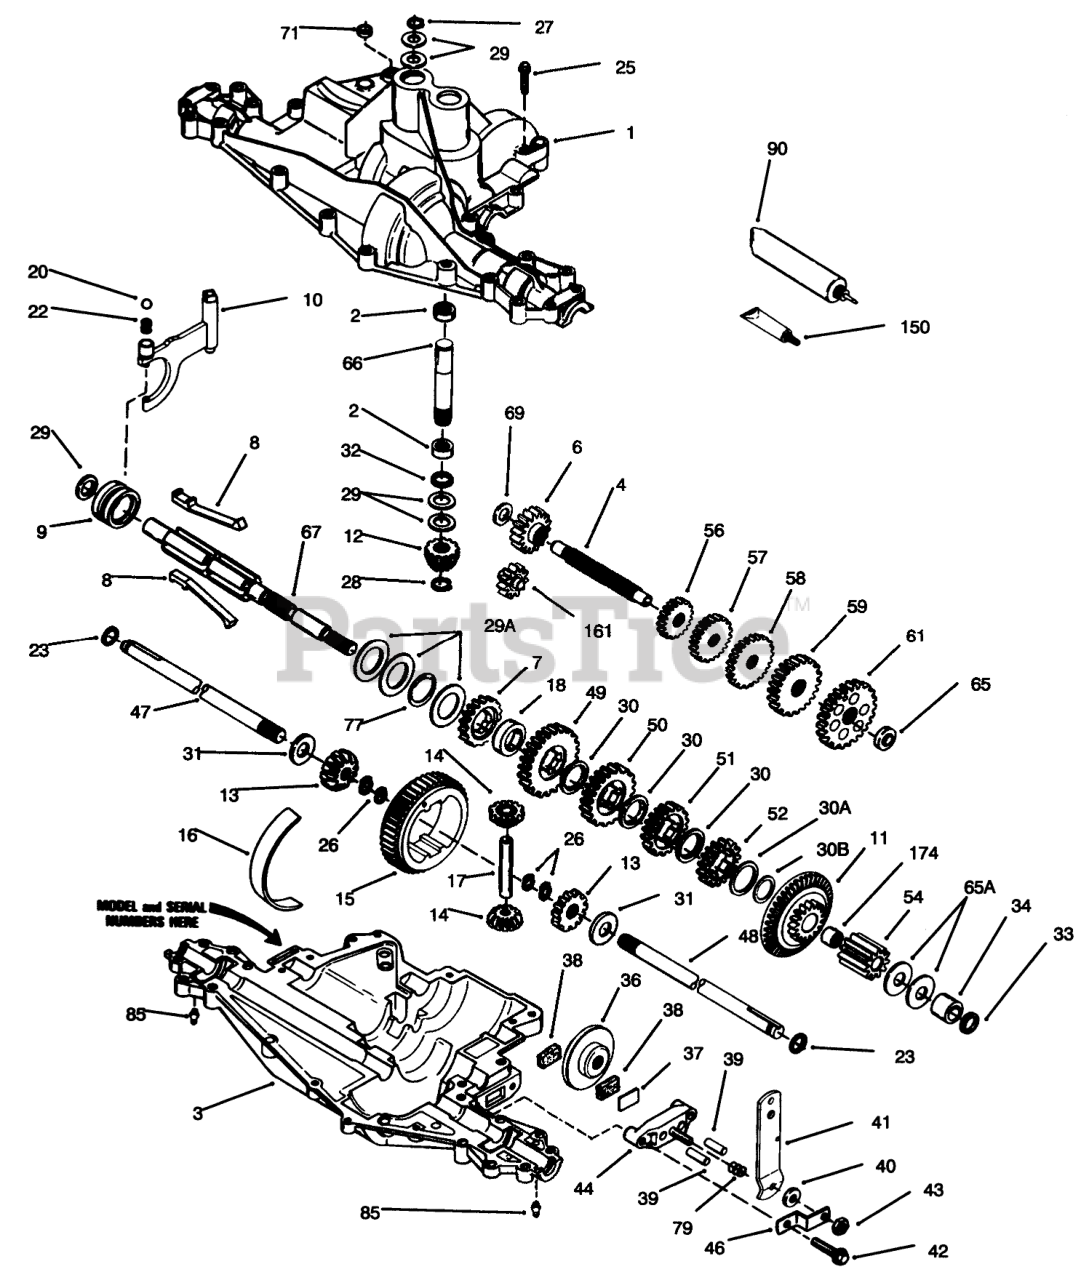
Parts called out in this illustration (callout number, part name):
1	Transaxle Cover
2	Bearing-Needle
3	Transaxle Case
4	Countershaft
6	Spur Gear (16 Teeth)
7	Gear-Spur (22 teeth)
8	Shift Key
9	Shift Collar
10	Shift Rod & Fork
11	Bevel Gear & Bearing (44/16 Teeth) (Incl. Ref. #174)
12	Bevel Pinion (14 Teeth)
13	Gear Bevel
14	Gear Pinion
15	Gear-Ring
16	Bearing Strip
17	Drive Pin
18	Neutral Spacer
20	Ball (3/8" dia.)
22	Spring
23	Ring-Seal
25	Ring Set (.020 O S)
26	Retaining Ring (pkg of 2)
27	Ring-Snap
28	Ring-Retainer
29	Washer
29A	Washer
30	Washer
30A	Washer
30B	Washer
31	Washer
32	O Ring
33	O-Ring
34	Bushing
36	Brake Disk
37	Brake Pad Plate
38	Brake Pad
39	Dowel Pin
40	Washer
41	Brake Lever
42	Ring Set (.020 O S)
43	Locknut
44	Nozzle-Carburetor
46	Bracket
47	Axle (16-3/4" Ig.)
48	Axle (11-9/16" lg.) (Incl. Ref. #26)
49	Gear-Spur, 30 Teeth
50	Gear-Spur, 25 Teeth
51	Gear-Spur (22 teeth)
52	Gear Spur 19t
54	Spur Gear (11 Teeth)
56	Gear-Spur, 20 Teeth
57	Gear-Spur, 25 Teeth
58	Gear-Spur (28 teeth)
59	Gear-Spur (30 teeth)
61	Spur Gear (34Teeth)
65	Washer
65A	Washer
66	Input Shaft (3.522" Ig.)
67	Shifter & Brake Shaft
69	Thrust Washer
71	Cut Seal-Square
77	Inverted Retaining Ring
79	Piston ASM (.020 O S)
90	Grease 32 Oz
150	Gasket Eliminator
161	Reverse Idler Assembly
174	Needle Bearing
